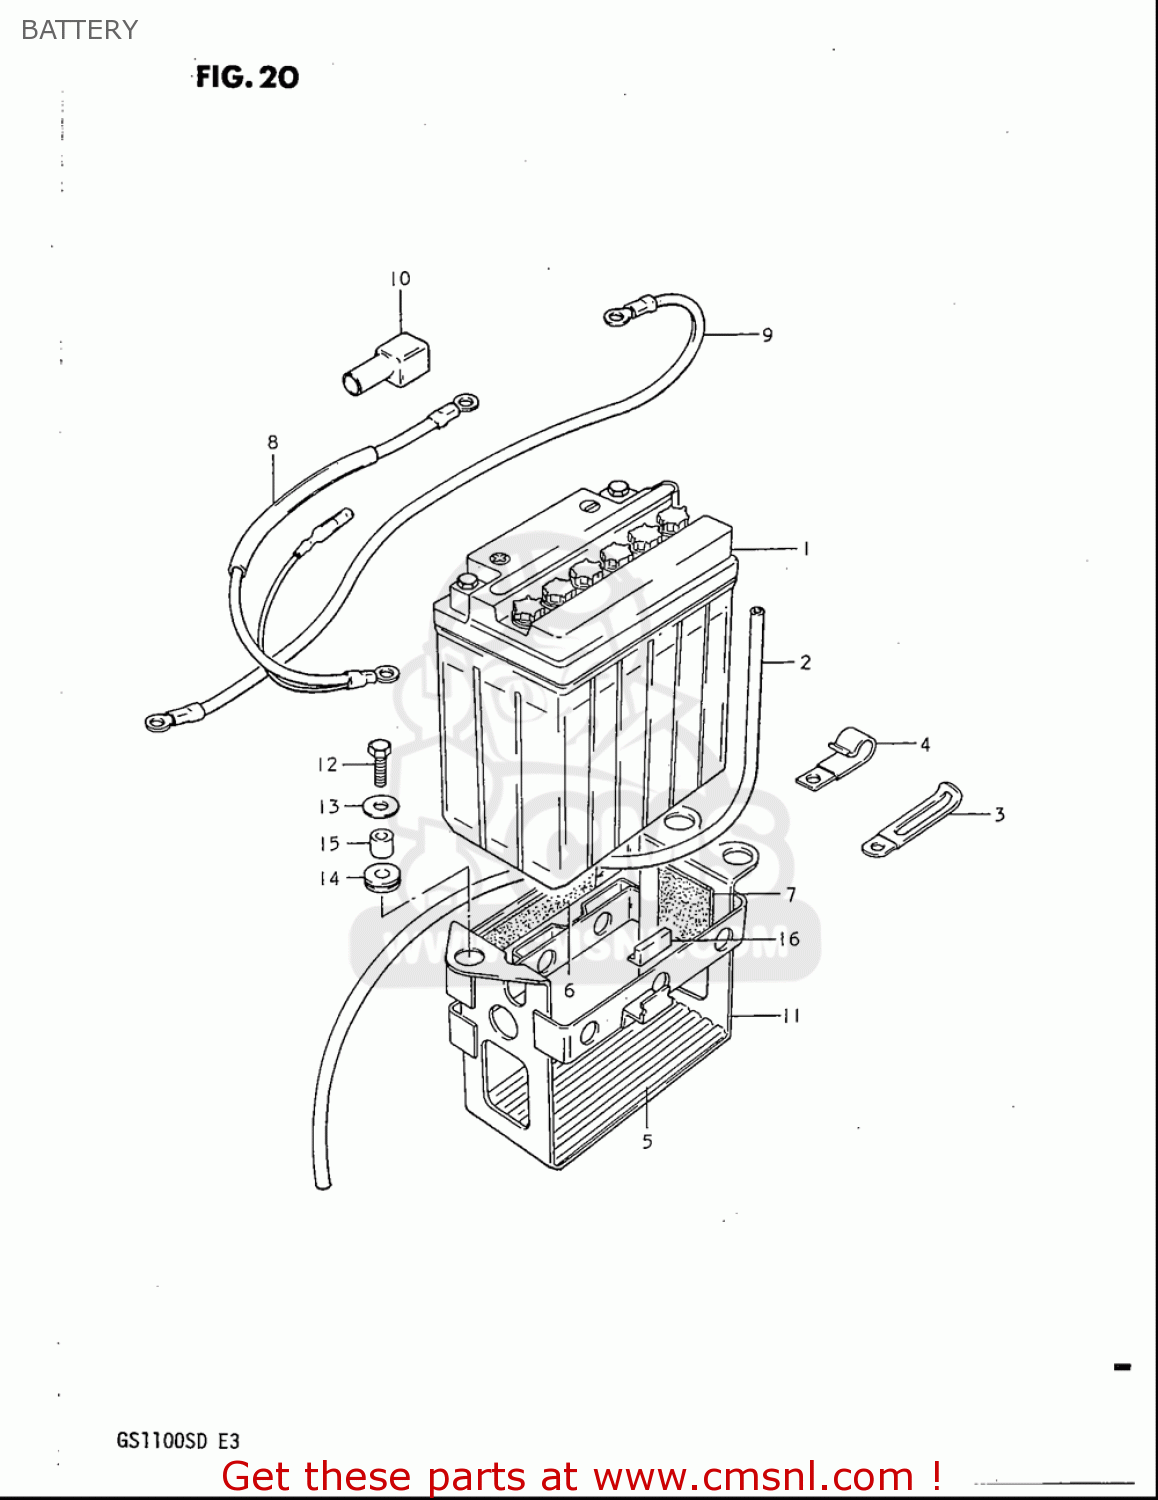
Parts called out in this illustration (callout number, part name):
1	BATTERY ASSY (12V)
2	HOSE,BATTERY EXHAUST
3	CLAMP(L:65)
4	CLAMP
5	PROTECTOR,BATTERY
6	PROTECTOR(170X95X3.0)
7	PROTECTOR(170X95X3.0)
8	WIRE,BATTERY PLUS
9	LEAD WIRE,BATTERY(-)
10	CAP,TERMINAL
11	HOLDER,BATTERY
12	BOLT
13	WASHER(6.5X20X1.6)
14	CUSHION
15	SPACER(6.1X9X7.5)
16	CUSHION,FRAME COVER
